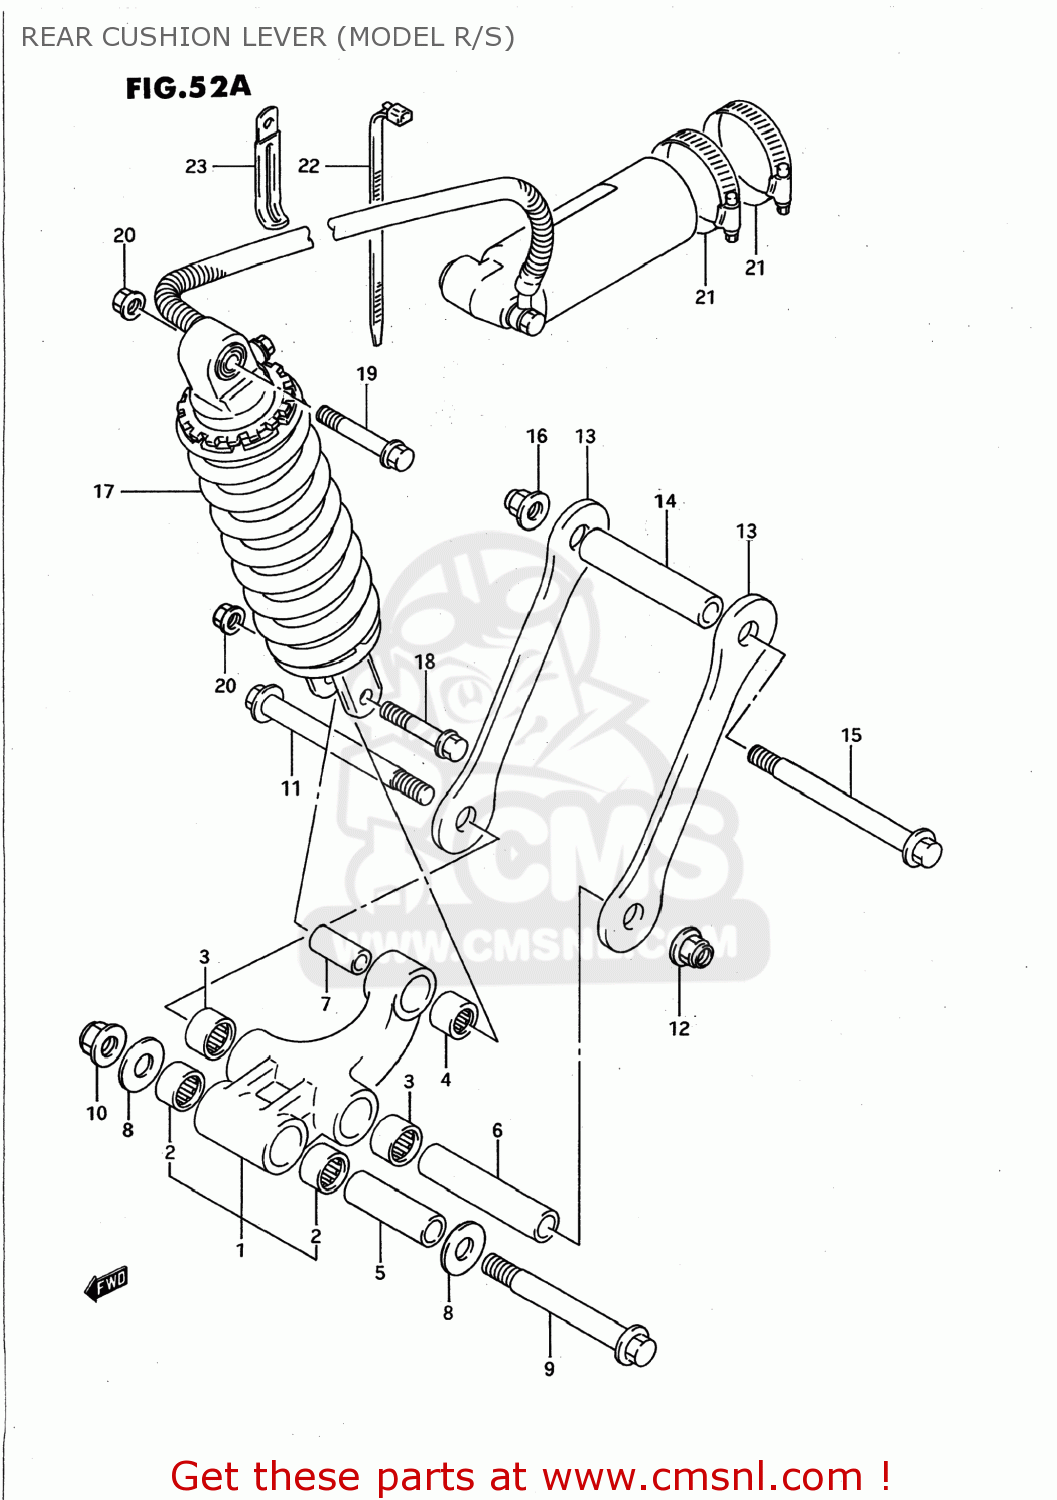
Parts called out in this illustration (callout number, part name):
1	LEVER SET,REAR CUSHION
2	BEARING(20X27X23.5)
3	BEARING(17X24X20)
4	BEARING(17X24X26)
5	SPACER,RR CUSHION LEVER
6	SPACER(12X17X85)
7	SPACER,RR CUSHION LEVER
8	WASHER
9	SHAFT,RR CUSHION LEVER FR
10	NUT
11	BOLT(12X115)
12	NUT 12MM
13	ROD,REAR CUSHION
14	SPACER(12X17X85)
15	BOLT(12X115)
16	NUT 12MM
17	ABSORBER ASSEMBLY,REAR SHOCK
18	BOLT(10X54)
19	BOLT(10X75)
20	NUT
21	CLAMP
22	CLAMP L:165
23	CLAMP(L:80)
